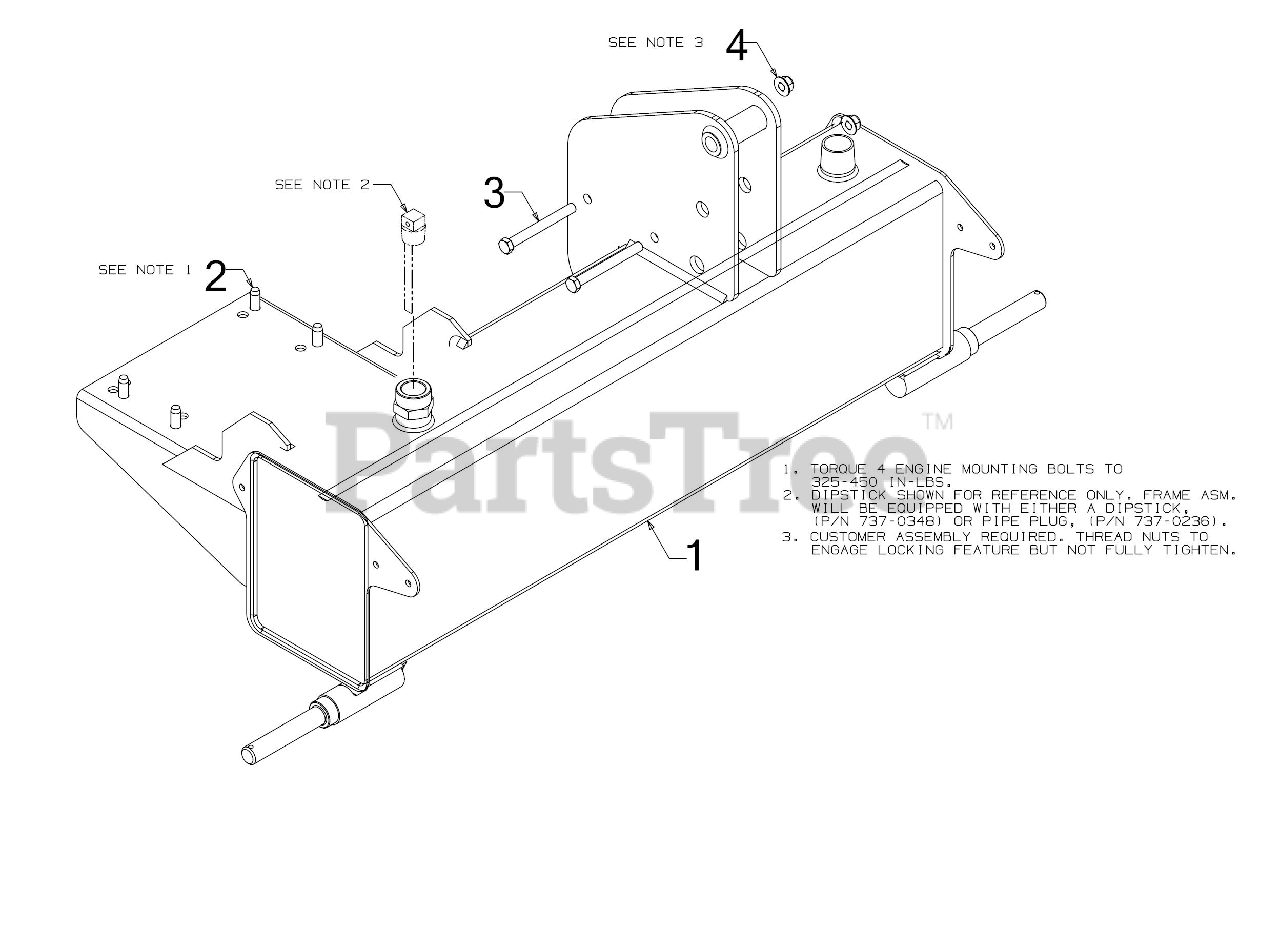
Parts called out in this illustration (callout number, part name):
1	TANK ASSEMBLY
2	SCREW 3/8-16 x 1
3	SCREW 3/8-16 x 3.50 GR5
